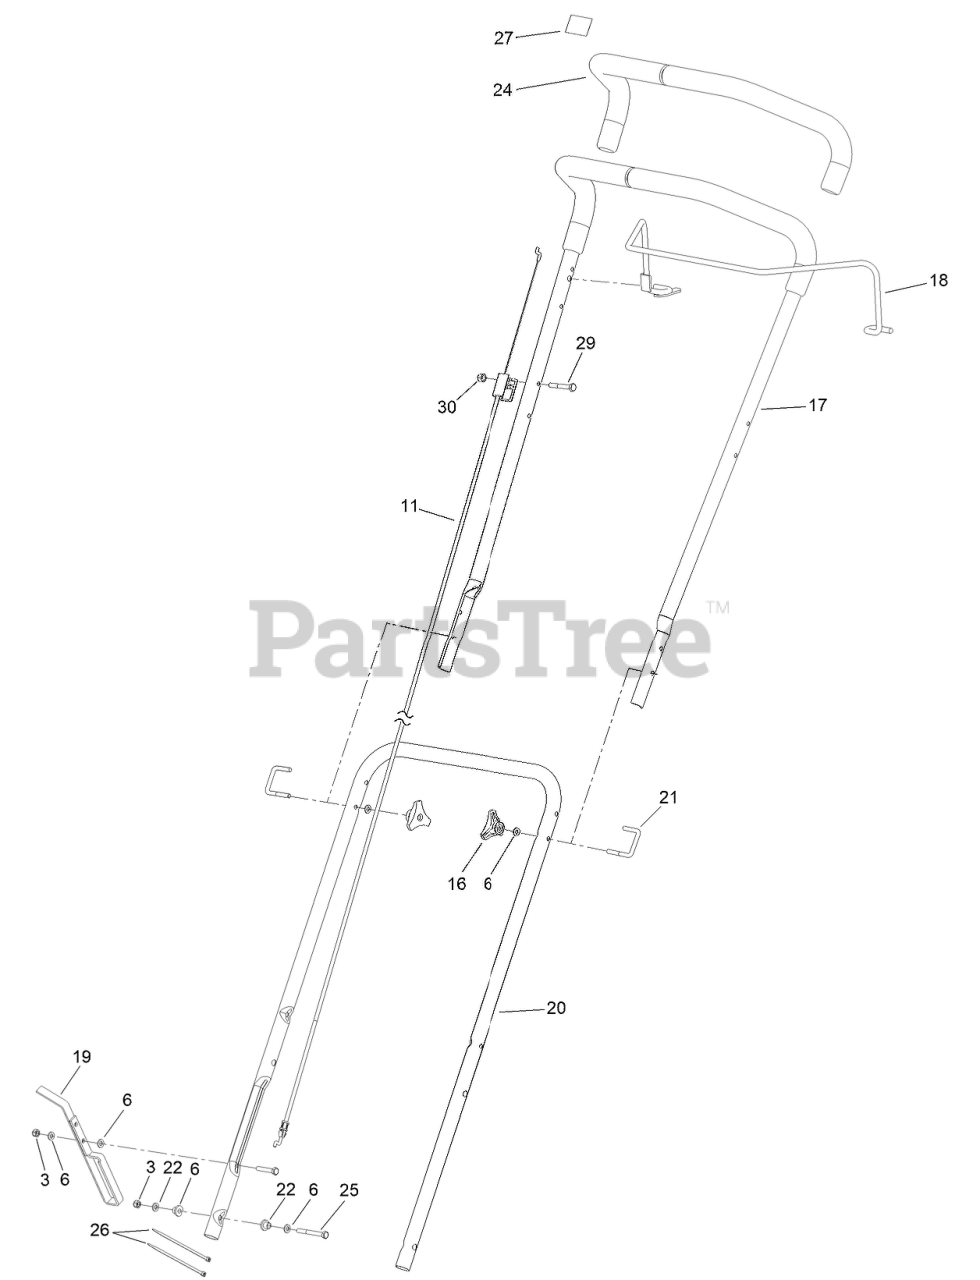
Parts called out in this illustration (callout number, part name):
3	NUT-NYLOC
6	WASHER-PLAIN
11	OPC CABLE
16	HANDWHEEL
17	HANDLE-UPPER
18	ARM-BAIL
19	FOOTSTOP
20	HANDLE-LOWER
21	BOLT-U
22	SPACER-HANDLE
24	GRIP-HANDLE
25	BOLT-HEX
26	TIE-CABLE
27	DECAL-STOP
29	BOLT
30	NUT-HEX
